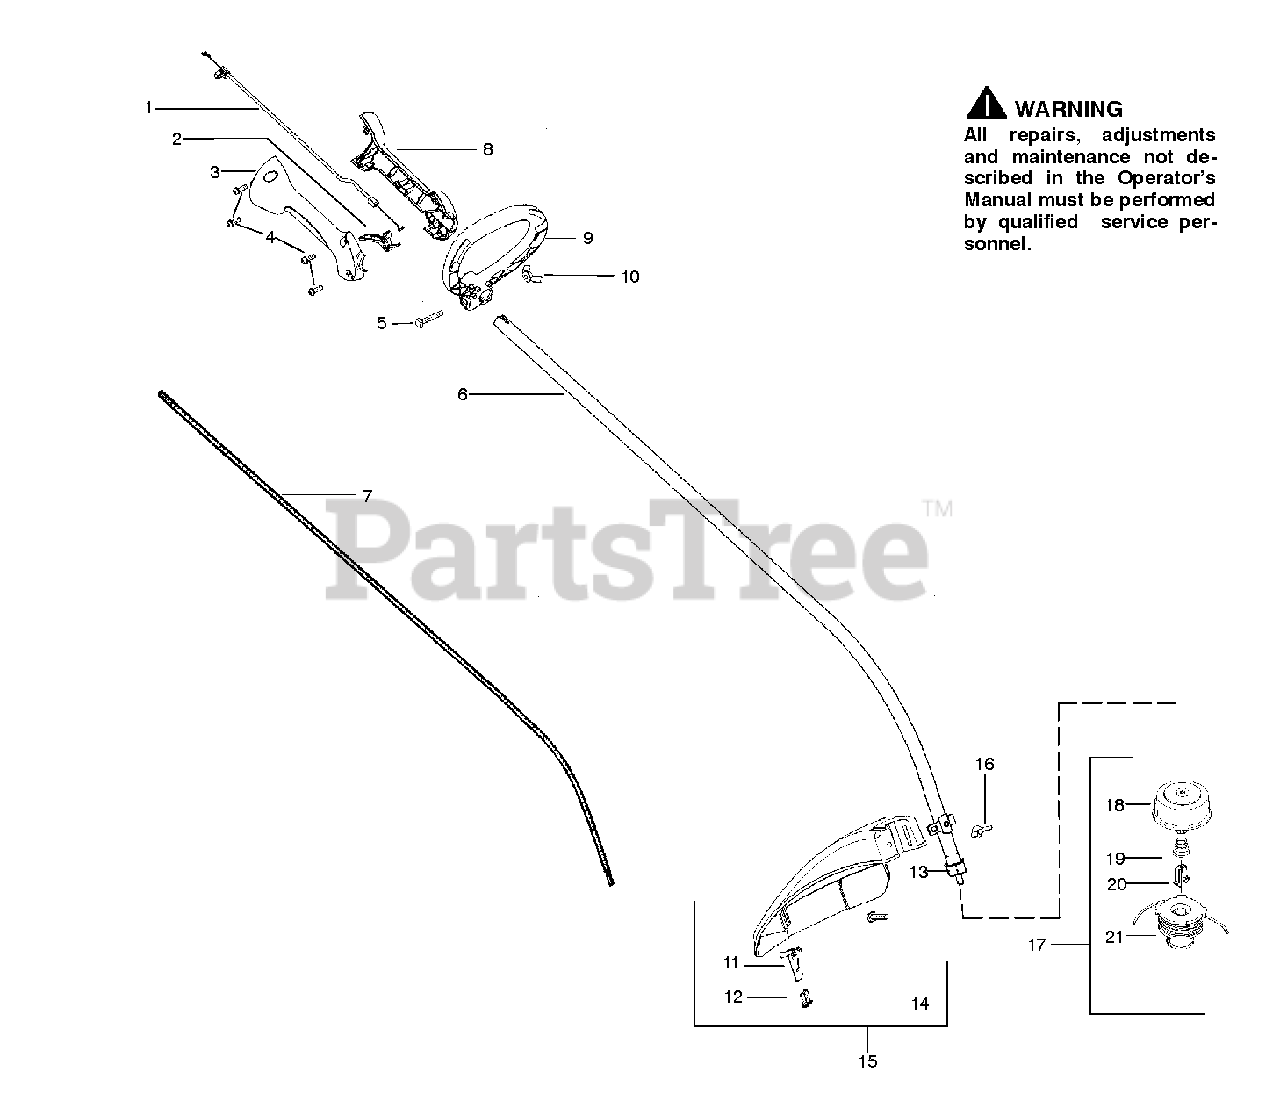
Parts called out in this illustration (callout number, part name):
1	ASSY THROTTLE CABLE
2	TRIGGER RED
3	HSG THROTTLE RH
5	BOLT\-1/4-20X1-1/2
6	KIT D'SHAFT 51" SILVER
7	DRIVE SHAFT
8	HSG THROTTLE LH
9	ASSY ASSIST HANDLE
10	WINGNUT, TYPE 2
11	LINE CUTTER
12	SCREW - THROTTLE HOUSING
13	DUST CUP
14	BOLT, TYPE 2
15	KIT
16	WINGNUT, TYPE 2
17	ACY PLN TNG 6 RH 5/16".080 RND
18	TNG VI HUB ASSY 5/16" RH
20	RETAINER
21	TNG 6 RH .080X25' PLN
